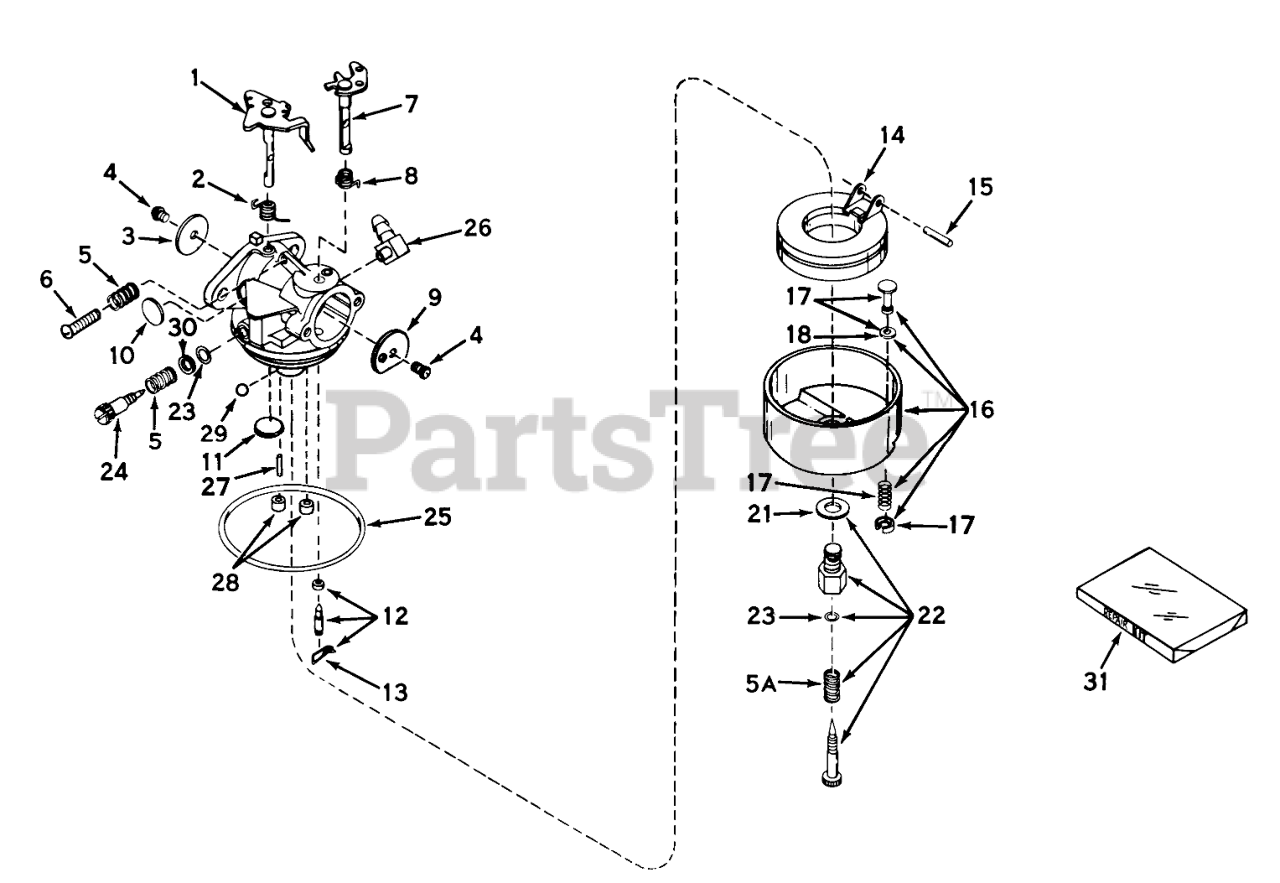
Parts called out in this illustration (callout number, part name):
1	Shaft/Lever-Throttle
2	Spring, Return
3	Shutter-Throttle
4	Screw-Shutter
5	Spring-Tension
6	Screw-Throttle Crack Screw / Idle Speed
7	Shaft& Lever Assy., Choke
8	Spring, Choke return
9	Shutter-Choke
10	Plug-Welch, Idle Mixture Well
11	Plug-Welch, Atmospheric Vent
12	Inlet Needle, Seat & Clip Assy.(Incl. No. 13)
13	Clip-Spring
14	Float,Carburetor
15	Shaft-Float
16	Bowl & Drain Assy., Float (Incl. No. 17)
17	Plunger Assy., Drain (Incl. No.18)
18	Gasket-Plunger, Drain
21	Washer-Bowl Nut
22	Adjustment Screw Assy., Main (Incl. Nos. 5A, 21 & 23)
23	"O"Ring
24	Screw, Idle Adj.
25	O Ring-Bowl, Float
26	Fitting Fuel Inlet
28	Plug, Cup
29	BalI, Steel
31	Repair Kit
